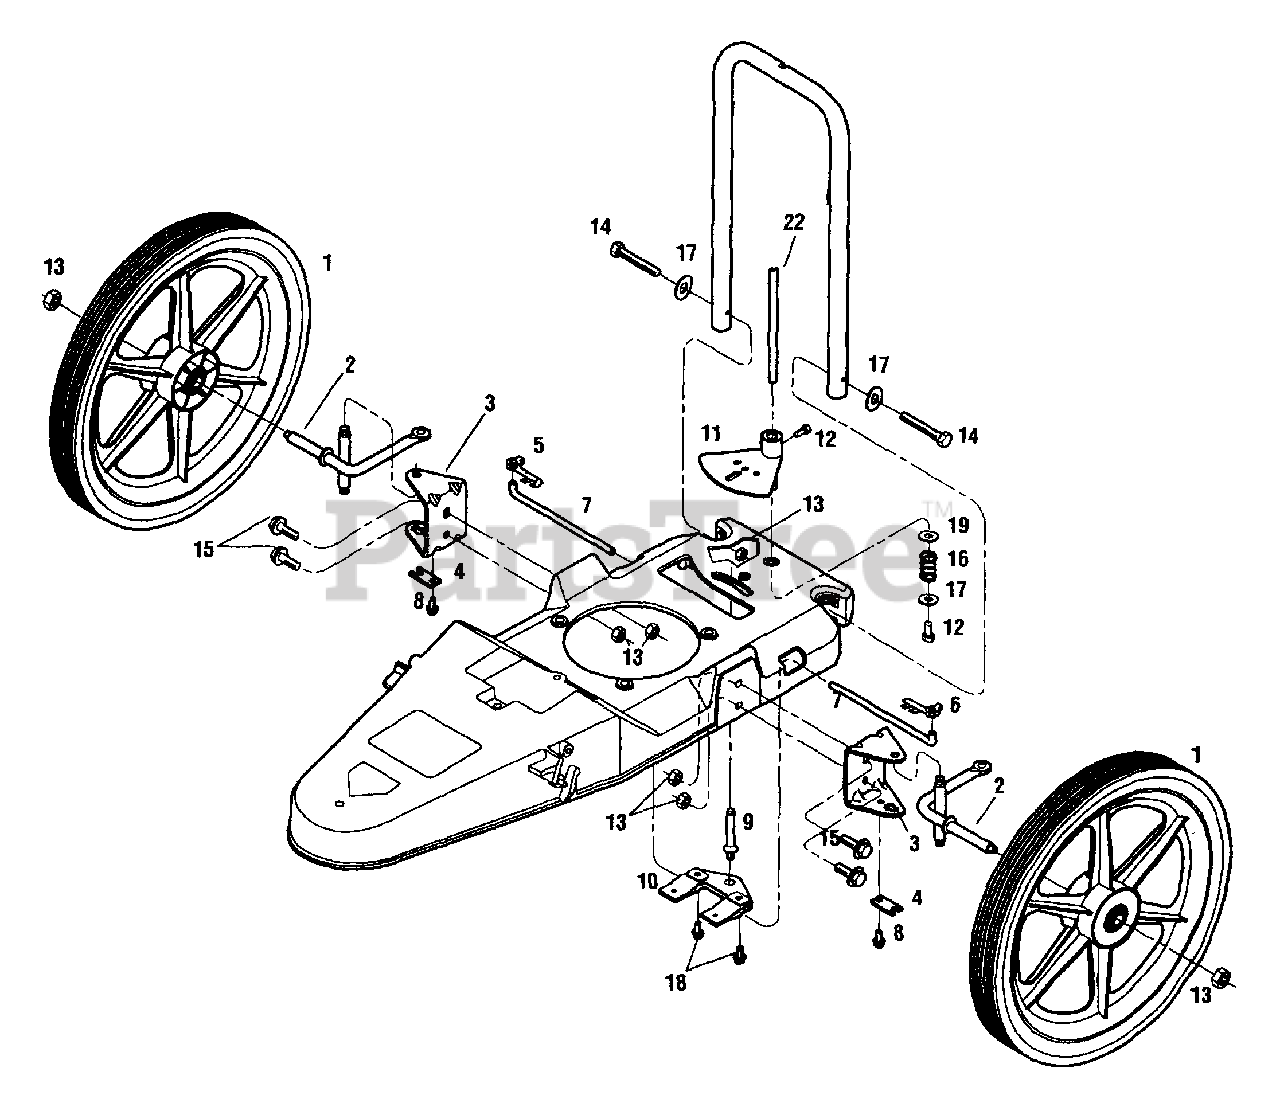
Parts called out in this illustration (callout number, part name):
1	Wheel - 6 spoke
2	Wheel Arm Weldment
3	Wheel Mounting Bracket
4	Wheel Arm Retainer
5	Rod End Clip/Right Side
6	Rod End Clip/Left Side
7	Steering Link
8	Hex Flange Screw, 1/4-20 x 5/8
9	Shoulder Stud
10	Clamp Link
11	Trim Plate
12	Screw, 5/16-24 x 1/2
13	Hex Lock Nut, 5/16-18
14	Hex Head Bolt, 5/16-18 x 2
15	Hex Flange Screw, 5/16-18 x 1
16	Spring
17	Washer, 5/16 ID
18	Hex Flange Screw, 5/16-18 x 5/8
19	Washer
22	Upper Steering Rod
